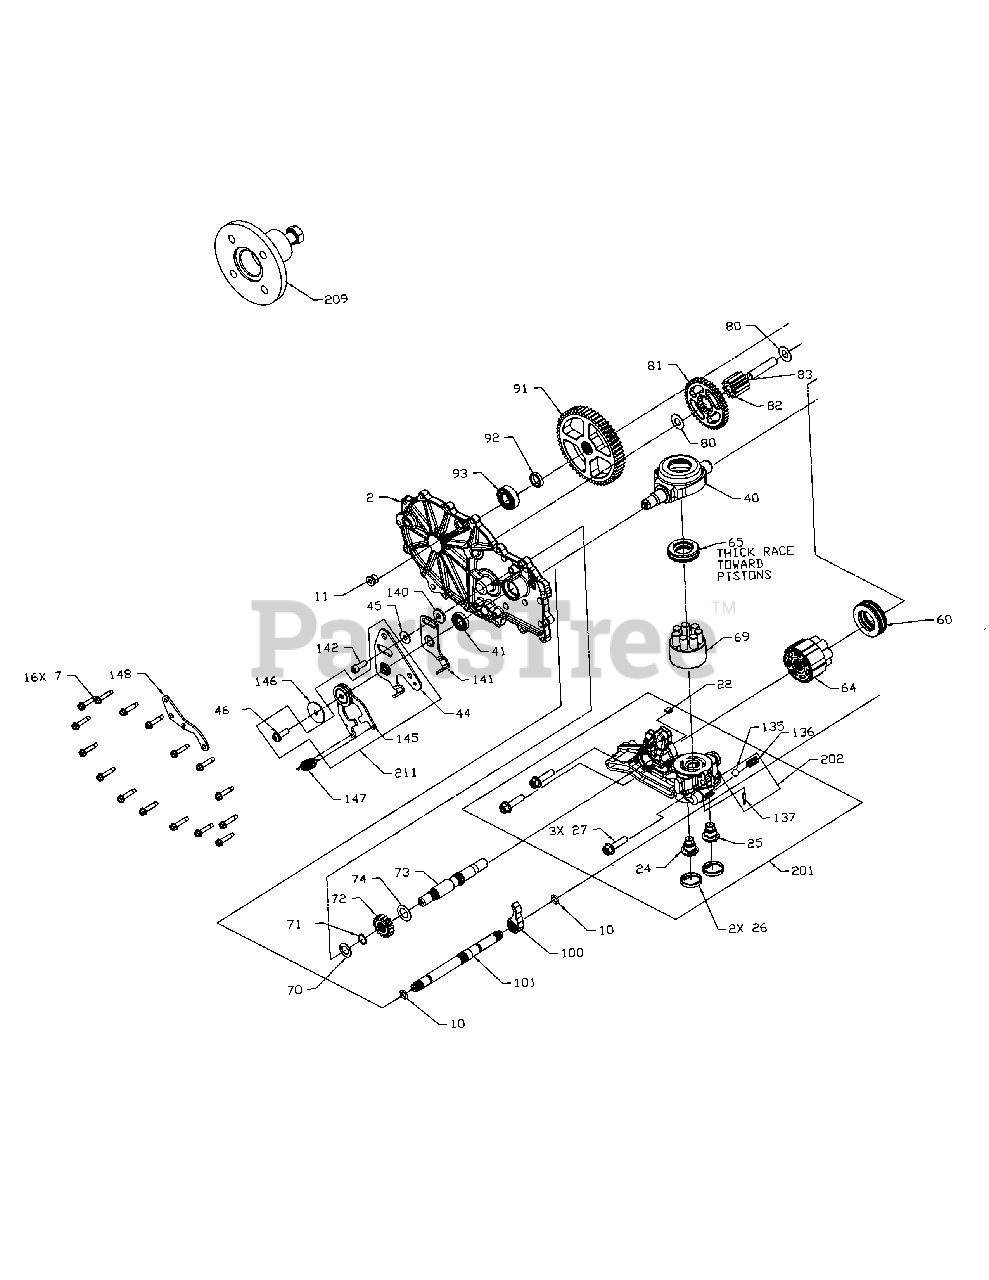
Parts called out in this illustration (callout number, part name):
1	Kit, Housing Main LH Chrg includes
1	Housing, Main LH Chrg
2	Kit, Cover Side LH Cntl includes
2	Cover, Side LH Cntl
7	HFHCS 1/4-20 x 1.25''
10	O-Ring 111.103 x .424
11	Plug 9/16/18 (Metal)
20	Center Section, LH Chrg
22	Plate, Bypass
23	Filter, Oil
24	Shock Valve
26	Seal, Plug 1.250 x .250
27	HFHCS 3/8-16 x 1.5 (Patch)
30	Seal, Lip .375 x .75 x .25
31	Ring, Ret .375 External
32	Rod, Bypass
33	Ring, Ret .750 Internal
34	Arm, Bypass
35	Ring, Rtng .375 Ext
40	Trunnion, Swashplate
41	Seal, Lip 18 x 32 x 7
44	Arm, Control - LH
45	Washer .34 x .88 x .06
46	TWHCS 5/16-24 x 1.00 (Patch)
52	Shaft, Input
53	Brg, Ball 17 x 40 x 12 Open 6203
54	Ring, Ret Wire .561 ID
55	Washer 1.23 x 1.56 x .04
56	Seal, Lip 17 x 40 x 7
57	Ring, Ret 2.06 Internal
60	Bearing, Thrust
64	Cylinder Block Assembly 16cc
65	Bearing, Thrust Ball 30 x 52 x 13
69	Block 7 Piston Assembly
70	Washer .63 x 1.0 x .05
71	Ring, Ret 62 External
72	Gear, 16T
73	Shaft, Motor
74	Washer .72 x 1.16 x .04
80	Washer .5 x 1.0 x .03
81	Gear, 43T
82	Gear, 11T
83	Jack Shaft (Pin)
90	Ring, Ret 2.06 Internal
91	Gear, 54T
92	Spacer, .750 x 1.000 x .257
93	Bearing Ball .75 x 40 x 12
94	Shaft, Axle
95	Bearing Ball 1.0 x 52 x 15 Open 6205M
96	Seal, Lip 25 x 52 x 10 TC (Gray)
97	Hub, 4 Stud (3.56 Taper)
99	Nut, Hex Lock 3/4-16
100	Pawl, Brake
101	Shaft, Brake
102	Handle, Brake
103	Clip, Retaining
105	HFHCS 1/4-20 x .75
106	Guard, Filter - LH
111	Fitting, Str 9/16-18 SAE .5 Barb
120	Fan, 7'', 10 Blade
121	Pulley 4.5 Inch
122	Nut, Hex Lock 1/2-20 Nylon
123	HFHCS 1/4-20 x .75
130	Tube, Connecting
131	Gerotor Assembly (1.6 cc/rev)
132	O-Ring, -137, 0.103 x 2.050
133	Cover, Charge Pump
134	HFHCS 1/4-20 x .75
140	Spacer, .320 x 1.005 x .179
141	Arm, Neutral LH
142	SHCS 5/16-24 x 1 (Patch)
145	Assembly, RTN
146	Washer, .343 x 1.500 x .062
147	Spring, Extension .57 x 2''
148	Bracket Damper
200	Kit, Seal
201	Kit, Center Section, LH Chrg
202	Kit, Chrg Relief
203	Kit, Charge
206	Kit, Hub 4 Bolt
207	Kit, Fan/ Pulley
209	Hub Puller, 4 Bolt
210	Kit, Input Shaft
211	Kit, RTN Bidirectional LH
212	Kit, Axle Shaft
